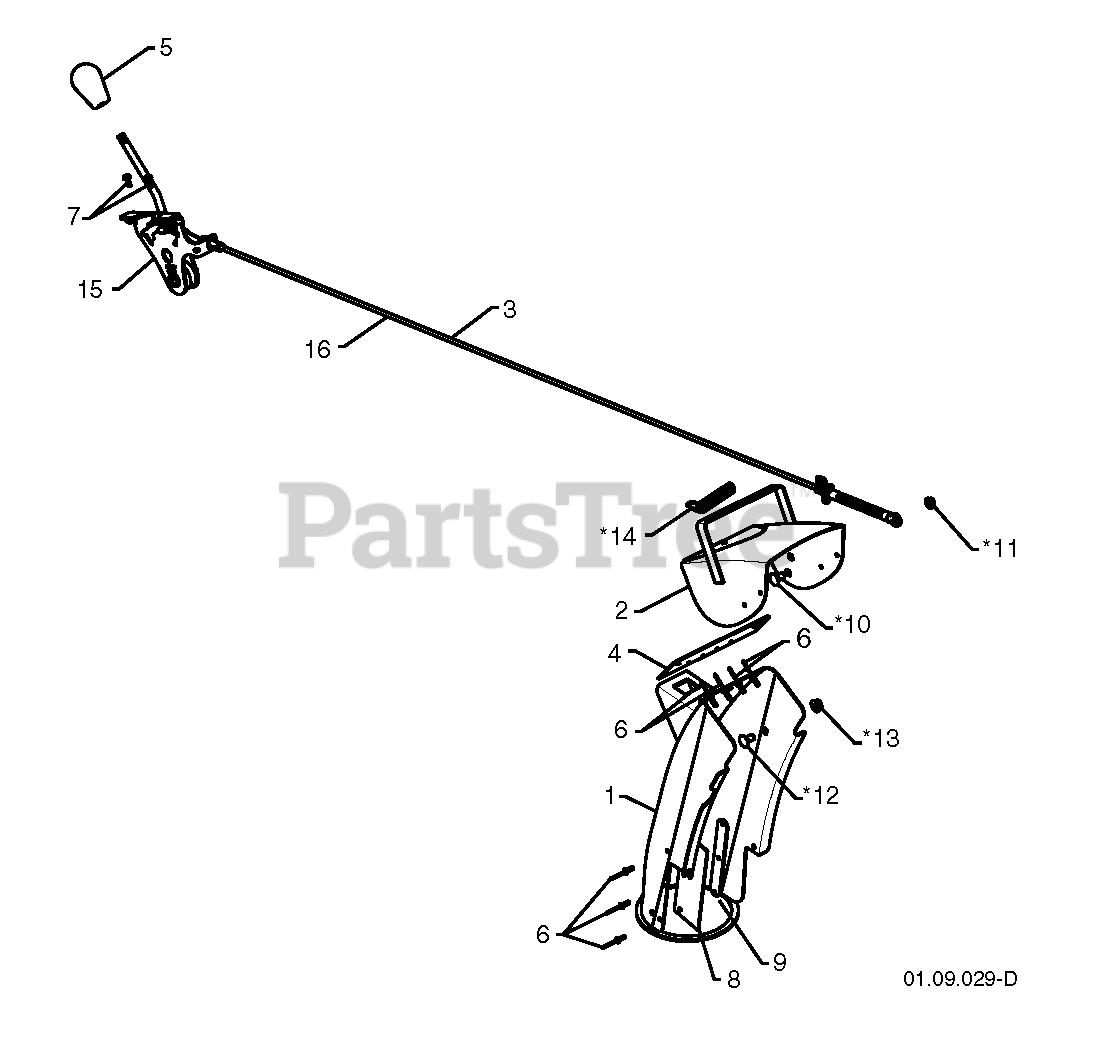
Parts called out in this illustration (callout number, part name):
1	RP_CHUTE.WELDMENT.SNOW.ORANGE
2	DEFLECTOR.WELDMENT.PNT.ORANGE
3	RP CRTL.ASM.DEFLECTOR.BLACK.SN
4	SEAL.DEFLECTOR
5	KNOB.OVERMOLD.DS.HUSQVARNA/BLK
6	RIVET BLIND
8	SHIELD.SNOW.CHUTE
9	STRAP.SHEILD.RETAINER
10	BOLT, SHOULDER
11	NUT.HEX.FLANGE.1/4
12	BOLT CAR BLK 5/16-18 X 5/8
13	NUT.LOCK.5/16-18
14	SPRING.DEFLECTOR.REM.CHUTE
15	CABLE.DEFLECTOR.SNOW
16	RP CABLE.DEFLECTOR.BOWDEN
